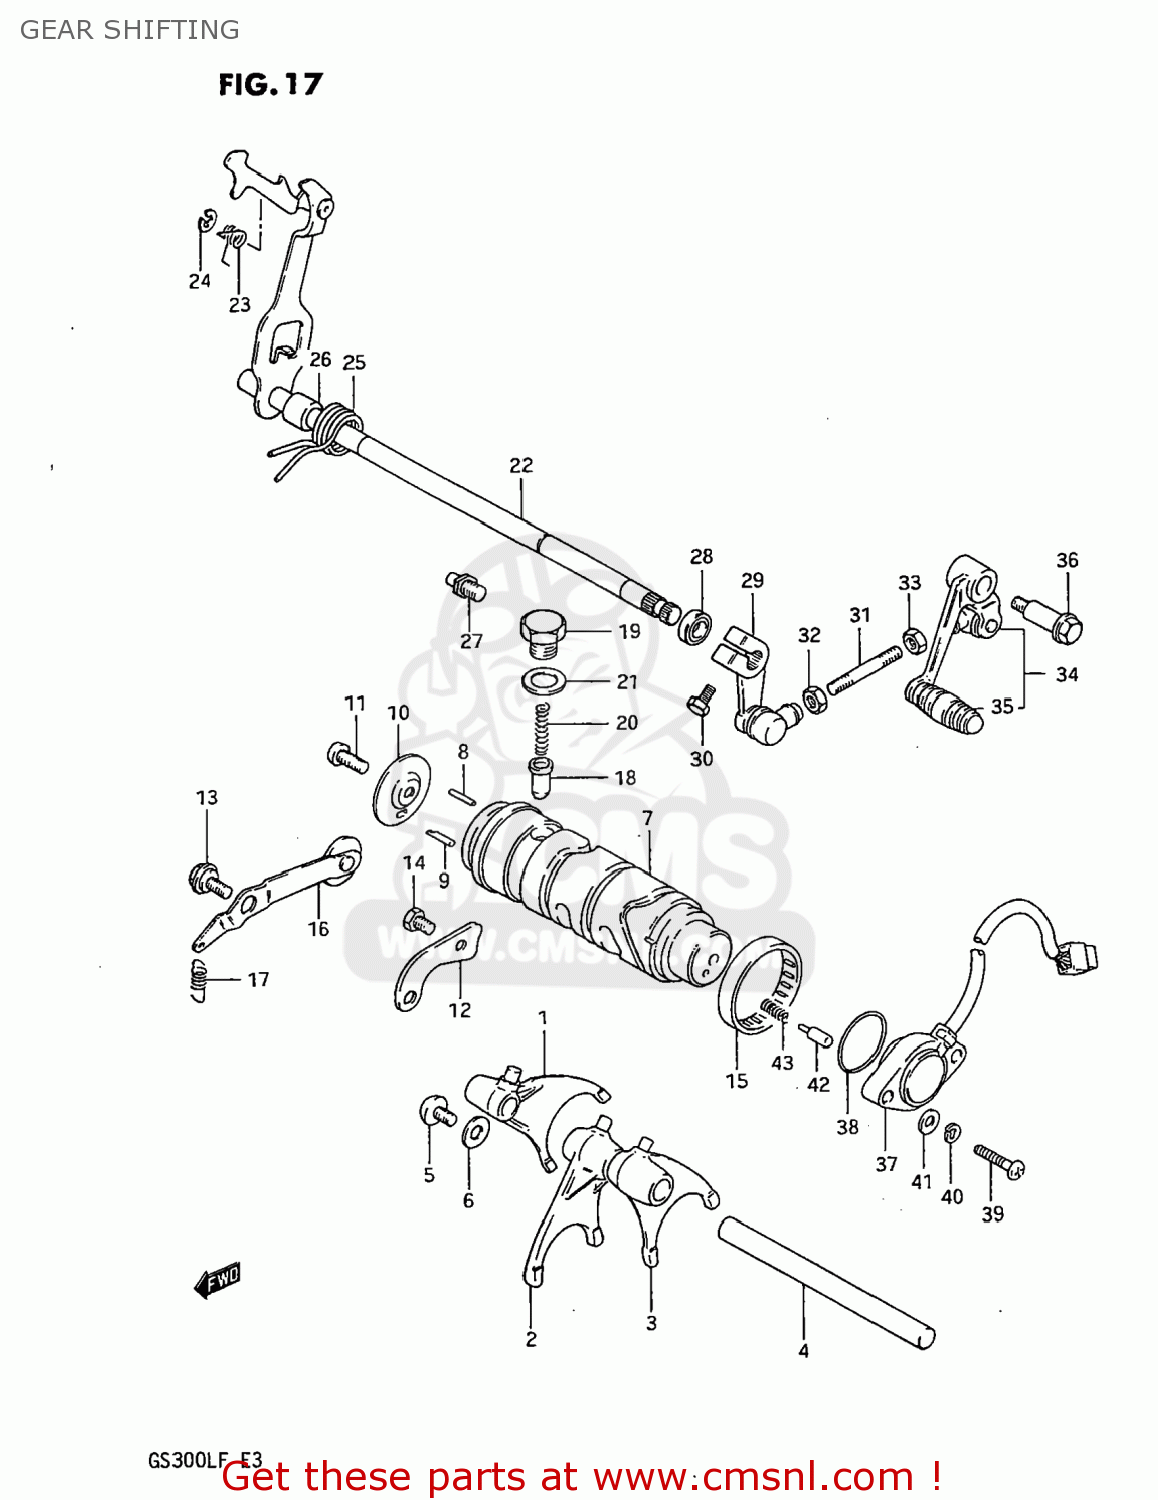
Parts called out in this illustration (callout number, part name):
1	FORK,GEAR SHIFT NO.1
2	FORK,GEAR SHIFT NO.2
3	FORK,GEAR SHIFT NO.3
4	SHAFT,GEAR SHIFT FORK
5	SCREW
6	WASHER
7	CAM,GEAR SHIFT
8	PIN(4X18.5)
9	PIN
10	RETAINER,GEAR SHIFT CAM DR PIN
11	SCREW
12	GUIDE,GEAR SHIFT CAM
13	BOLT
14	BOLT
15	BEARING(40X47X12)
16	STOPPER,GEAR SHIFTING
17	SPRING
18	STOPPER,GEAR SHIFT CAM NO.2
19	HOLDER,GEAR SHIFT CAM STOP SPR
20	SPRING
21	GASKET(14X19.2X2) (NAS)
22	SHAFT,GEAR SHIFT
23	SPRING
24	E RING
25	SPRING
26	SPACER(12X20X15.3)
27	STOPPER,GEAR SHIFT CAM
28	OIL SEAL
29	ARM,GEAR SHIFT LINK
30	BOLT
31	ROD,GEAR SHIFT LINK
32	NUT
33	NUT
34	LEVER ASSY,GEAR SHIFT
35	RUBBER,GEAR SHIFT PEDAL
36	SHAFT,GEAR SHIFT LEVER
37	BASE ASSEMBLY,NEUTRAL SWITCH TERMINAL
38	O-RING (D:2.4 ID:26.2)
39	SCREW
40	LOCK WASHER
41	WASHER
42	PIN(5X15.5)
43	SPRING
